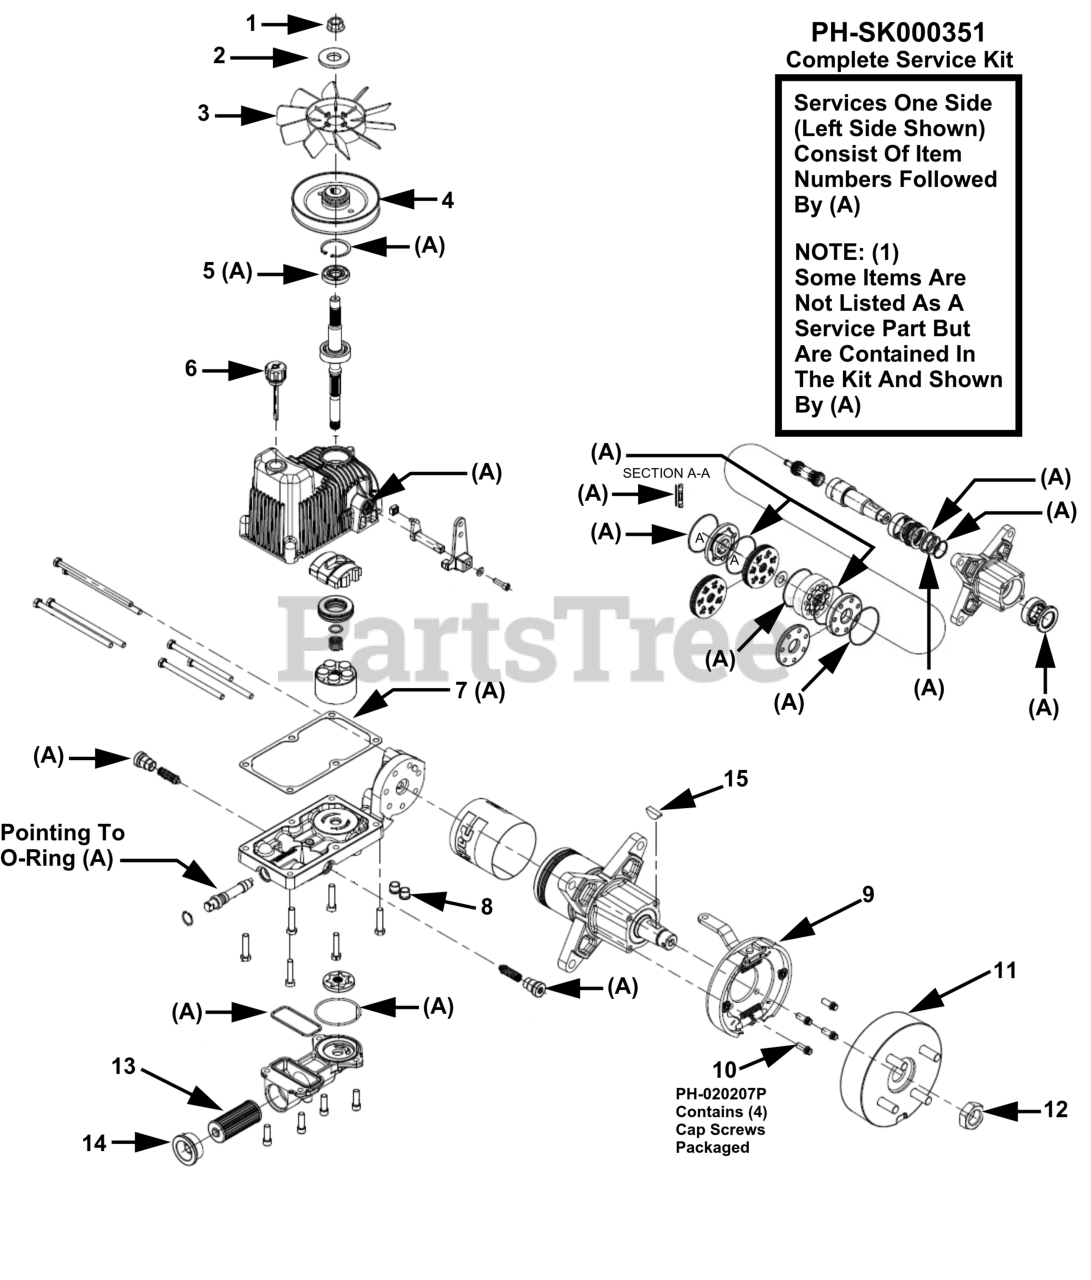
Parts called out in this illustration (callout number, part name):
1	NUT-FLANGE 1/2-20
2	FAN SPACER
4	PULLEY (SPLINED)
6	BREATHER
8	PLUG-MAGNETIC HEX
9	BRAKE ASSEMBLY-ON HOLE LEVER
10	SCREW-CAP (QTY 4)
11	DRUM-4 BOLT BRAKE
12	LOCK NUT - 1-20
14	PLUG & O-RING ASSE
15	WOODRUFF KEY
A	COMPLETE SEAL SERVICE KIT
